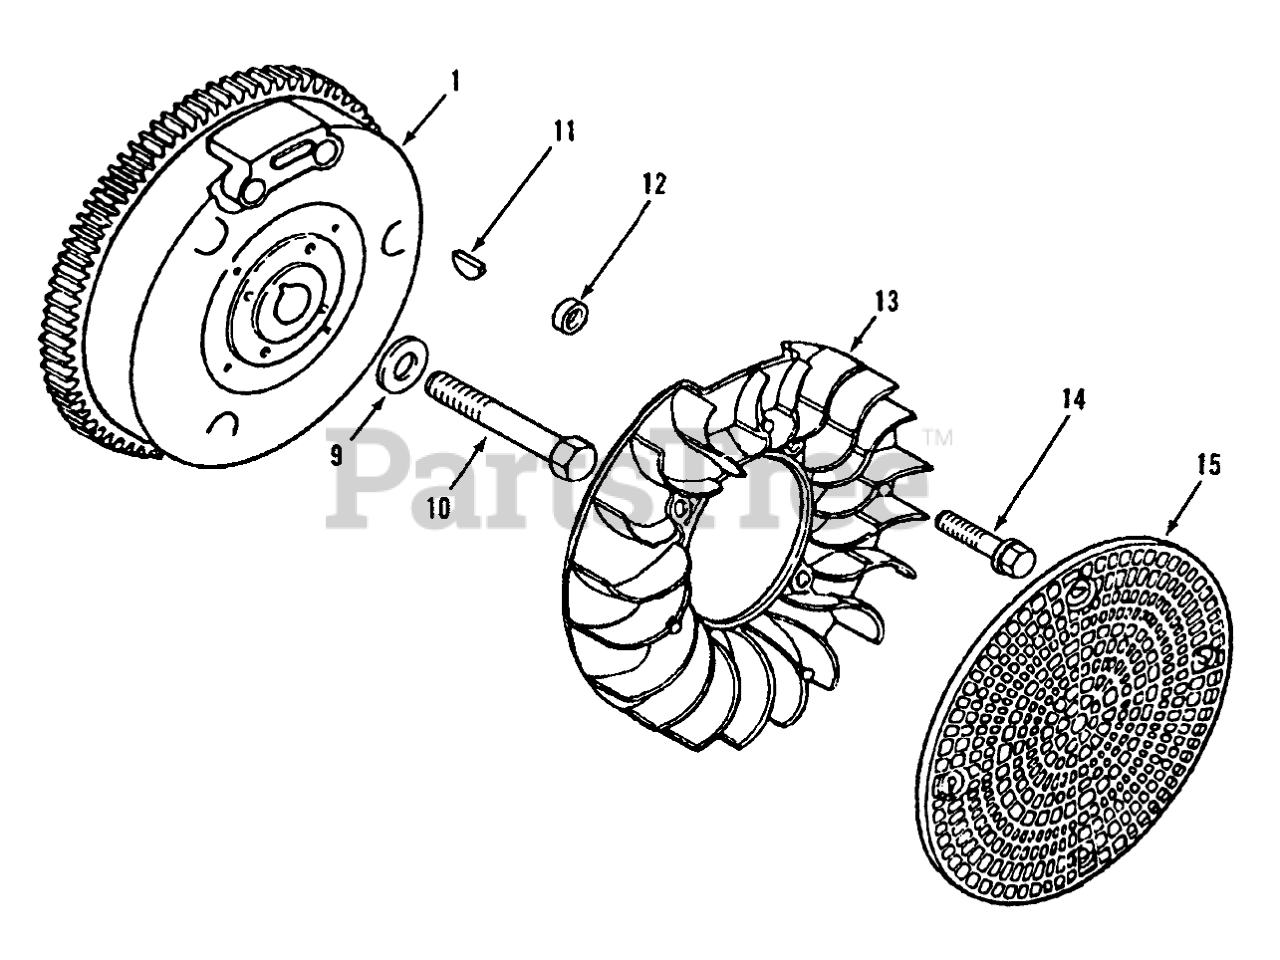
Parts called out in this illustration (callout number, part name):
1	Flywheel 310
1	Flywheel
9	Plain Washer 13/32 ID, 1-3/8 OD
10	Hex. Mach. Screw 3/8-24 x 1-1/8
11	Key-Woodruff
12	Spacer
14	Screw-Hex. Hd.
15	Screen
